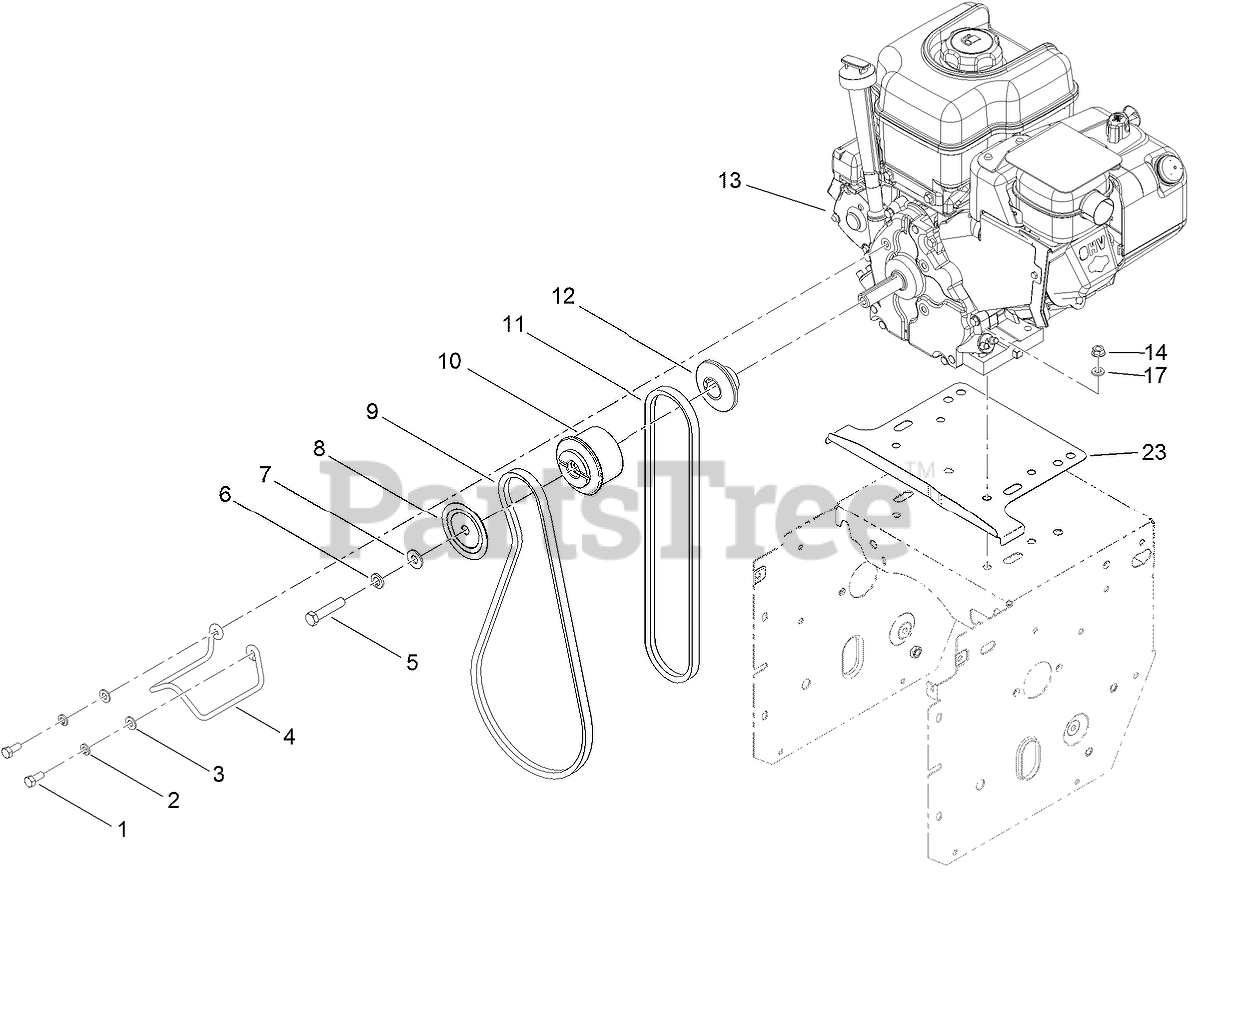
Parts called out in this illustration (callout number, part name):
1	SCREW-HH
2	WASHER-LOCK
3	WASHER-PLAIN
4	GUIDE-BELT
5	SCREW-HH
6	WASHER-LOCK
7	WASHER-FLAT
8	SHEAVE-HALF, IMPELLER
9	BELT-V
10	PULLEY-ENGINE, CENTER
11	V BELT-TRACTION
12	SHEAVE-HALF, TRACTION
14	NUT-HF
17	WASHER-FLAT
23	SHIELD-DRIVE
